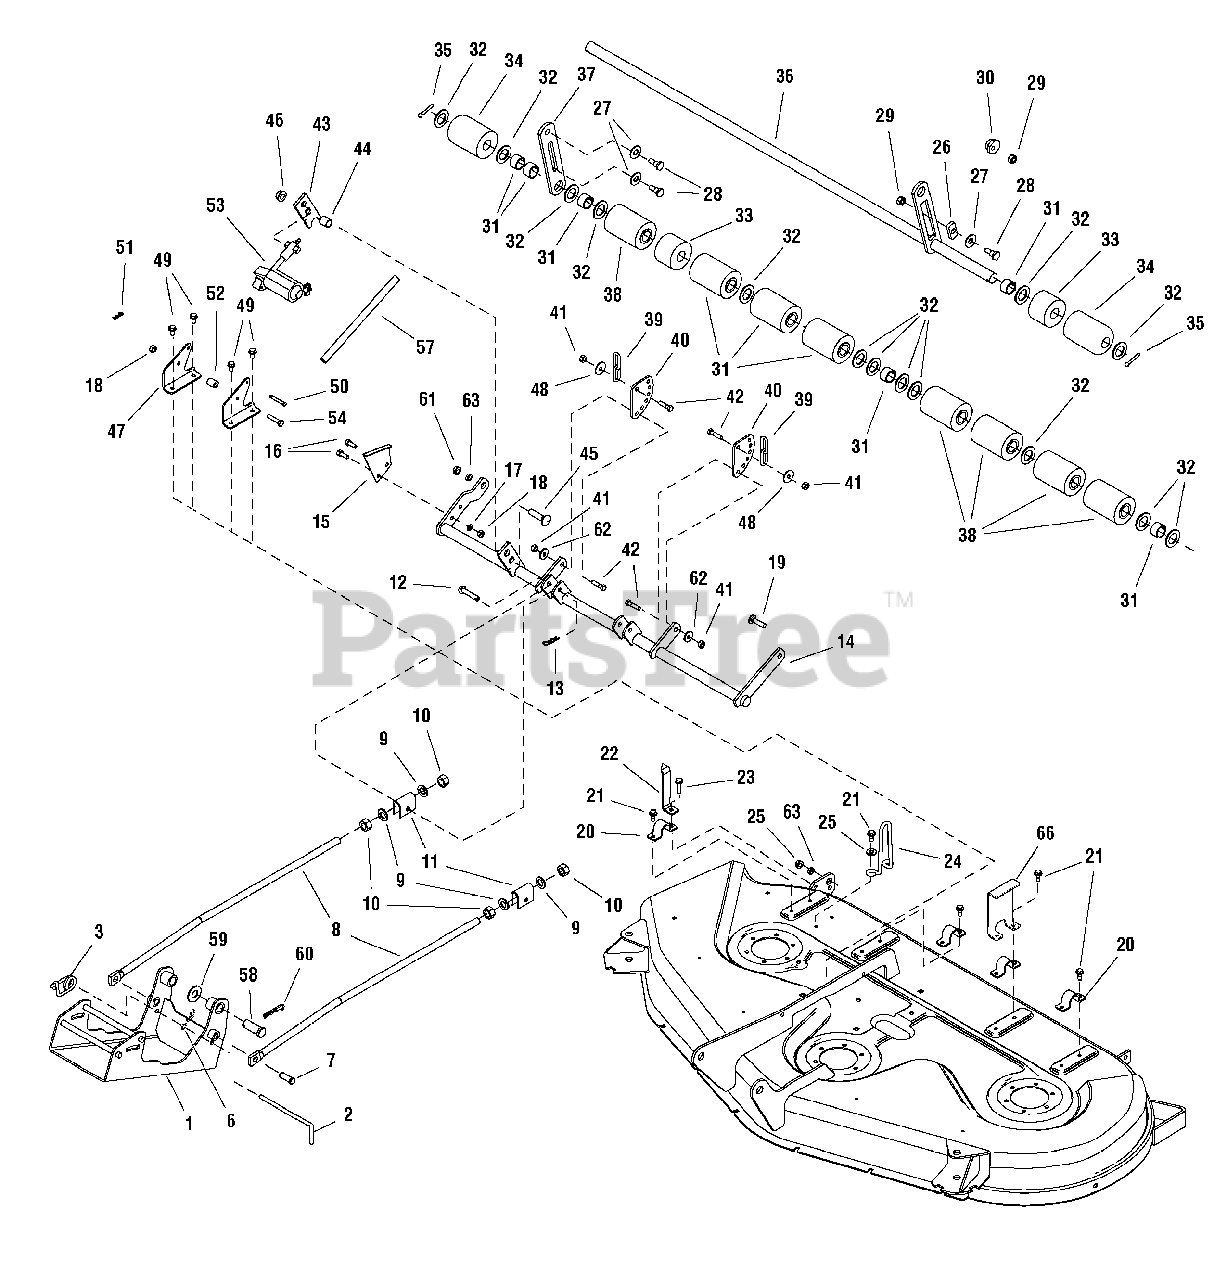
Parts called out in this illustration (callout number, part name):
1	HITCH & ROD ASSEMBLY, 54"
3	PIN, Spring
6	PIN, Cotter Locking
7	PIN, Yoke
8	ROD, Adjusting
9	WASHER, 5/8
10	NUT, Hex 5/8-11
11	TRUNNION
12	PIN, Round Head Drilled 3/8 x 2
13	CLIP, Hair Pin
14	SHAFT ASSEMBLY, Rocker 54"
15	BRACKET, Height of Cut
16	CAPSCREW, Hex Head 5/16-18 x 7/8 G5
17	LOCKWASHER, Spring 5/16
18	NUT, Hex 5/16-18
19	BOLT, Carriage, 3/8-16 x 1-1/2, G5
20	STRAP, Rod
21	SCREW, Hex Washer Head Taptite 5/16-18 x 3/4
22	INDICATOR, Height of Cut
23	CAPSCREW, Hex Washer Head Taptite 5/16-18 x 1-1/4
25	WASHER, 3/8
27	WASHER, 1/2
28	BOLT, Shoulder, 3/8-16 X 1.34
29	NUT, Hex Toplock Spiralock Flange 3/8-16
30	NUT, Hex Adjusting, .99 DIA .687
35	PIN, Cotter
36	SHAFT & BAR ASSEMBLY
37	BAR, Roller
38	ROLLER W/BUSHINGS
39	CHAIN, Link
40	BRACKET, Roller Adjust
41	NUT, Hex Lock ESNA Light 5/16-18
42	CAPSCREW, Hex Head 5/16-18 x 1-1/4 G5
43	ARM, Rocker
44	SPACER, .66 ID
45	CARRIAGE BOLT, 1/2-13 x 2 G5
46	NUT, Hex Toplock Flange 1/2-13
47	BRACKET, Mounting
48	WASHER, 5/16
49	CAPSCREW, Hex Washer Head Taptite 5/16-18 x 5/8
50	PIN, Shear
51	CLIP, Hairpin
52	SPACER, Powdered Metal
53	MOTOR, Electric Mini Actuator
54	CAPSCREW, Hex Head 5/16-18 x 1-1/2 G5
57	TUBE, Flexible
58	PIN, Clevis
59	WASHER, 3/4
60	CLIP, Hair Pin
61	NUT, Hex Flange 3/8-16 Machine Lock
62	WASHER, 5/16
